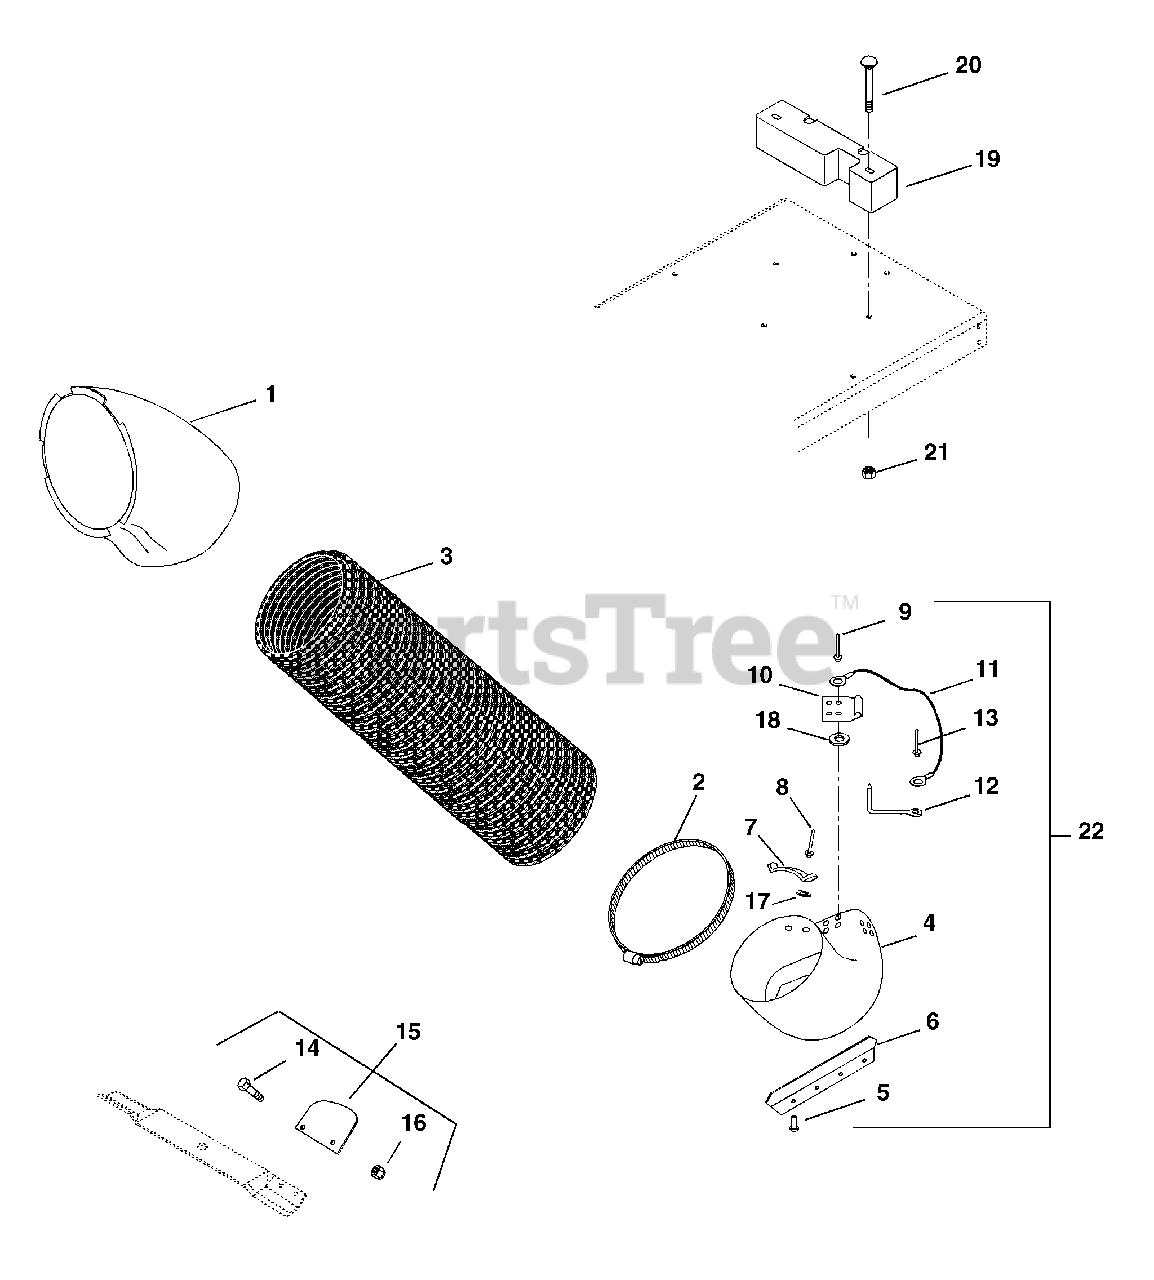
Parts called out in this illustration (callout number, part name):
1	Upper Boot
2	Hose Clamp
3	Hose 7 x 38
4	Lower Boot Assembly
5	Rivet - Tubular .187 x .375
6	Extension - Chute
7	Tube Retainer Clip
8	Rivet - Pop .187 x .527
9	Rivet - Pop .187 x .402
10	Boot Bracket
12	Pull Pin
13	Rivet - Tubular .187 x .375
14	Bolt-Hex .31-24 x .75 Grade 8
15	Vane Service Package
16	Nut-Locking Top .312-24
17	Washer-Flat-Steel .219 x .50 x .049
18	Washer-Flat-Steel .194 x .492 x .047
19	Counterweight
20	Bolt-Round Head Square Neck .44 -14 x 4.50 Grade 2
21	Nut .437-14
22	Mower Boot Assembly - 40"
